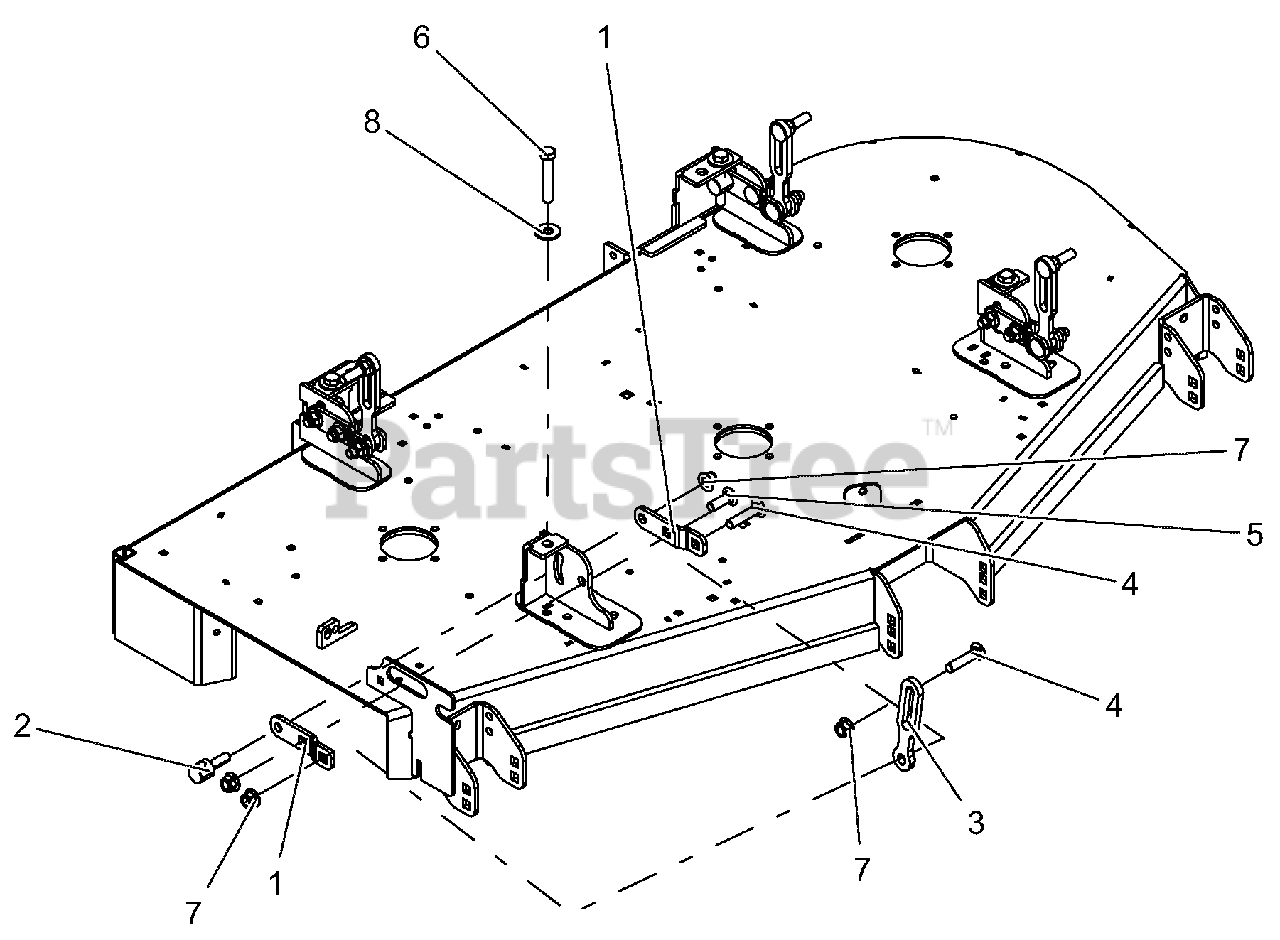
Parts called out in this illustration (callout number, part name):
1	BRKT, DECK LEVELING-BLACK
2	TRUNNION, .50-13
3	LINK, DECK LIFT
4	BLT-RDHDSQNK .50-13X2.25 G5 Y
5	@BLT-RDHDSQNK .50-13X1.50 G5 YWZC
6	BLT-HEX .50-13X3.00 GR5 FTH YZ
7	NUT-LK-NYL-FLG .50-13 YWZC
8	@WSHR-FL-STL.563X1.38X.109YWZC
